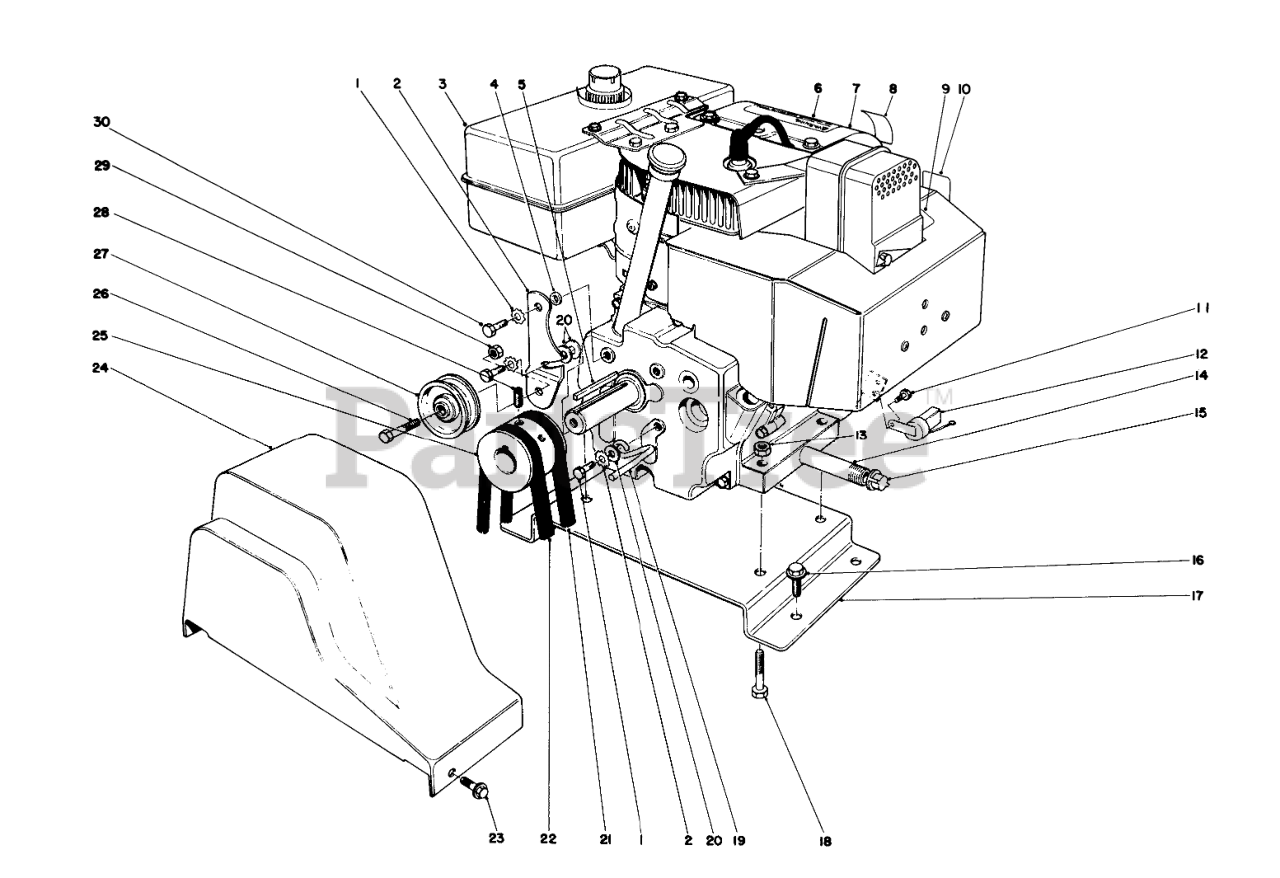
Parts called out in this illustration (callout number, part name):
1	WASHER-LOCK
2	ENGINE IDLER ARM
3	Fuel Tank w/Cap
4	SPACER
6	CAUTION DECAL
7	Engine
8	PRIMER DECAL
9	HOT SURFACE DECAL
10	CHOKE DECAL
11	SCREW-HWH
12	INTERLOCK MODULE
13	NUT-LOCK, NI
14	NIPPLE-PIPE
15	CAP-PIPE
16	SCREW-HHFTF
17	Plate ngine Mounting
18	SCREW-HH
19	BELT RETAINER
20	WASHER-PLAIN
21	V-BELT
22	V-BELT
23	SCREW-HWH
24	BELT GUARD
25	ENGINE PULLEY
26	SCREW-HH
27	PULLEY-IDLER
28	Screw-Set
29	NUT-LOCK, NI
30	SCREW-HH
